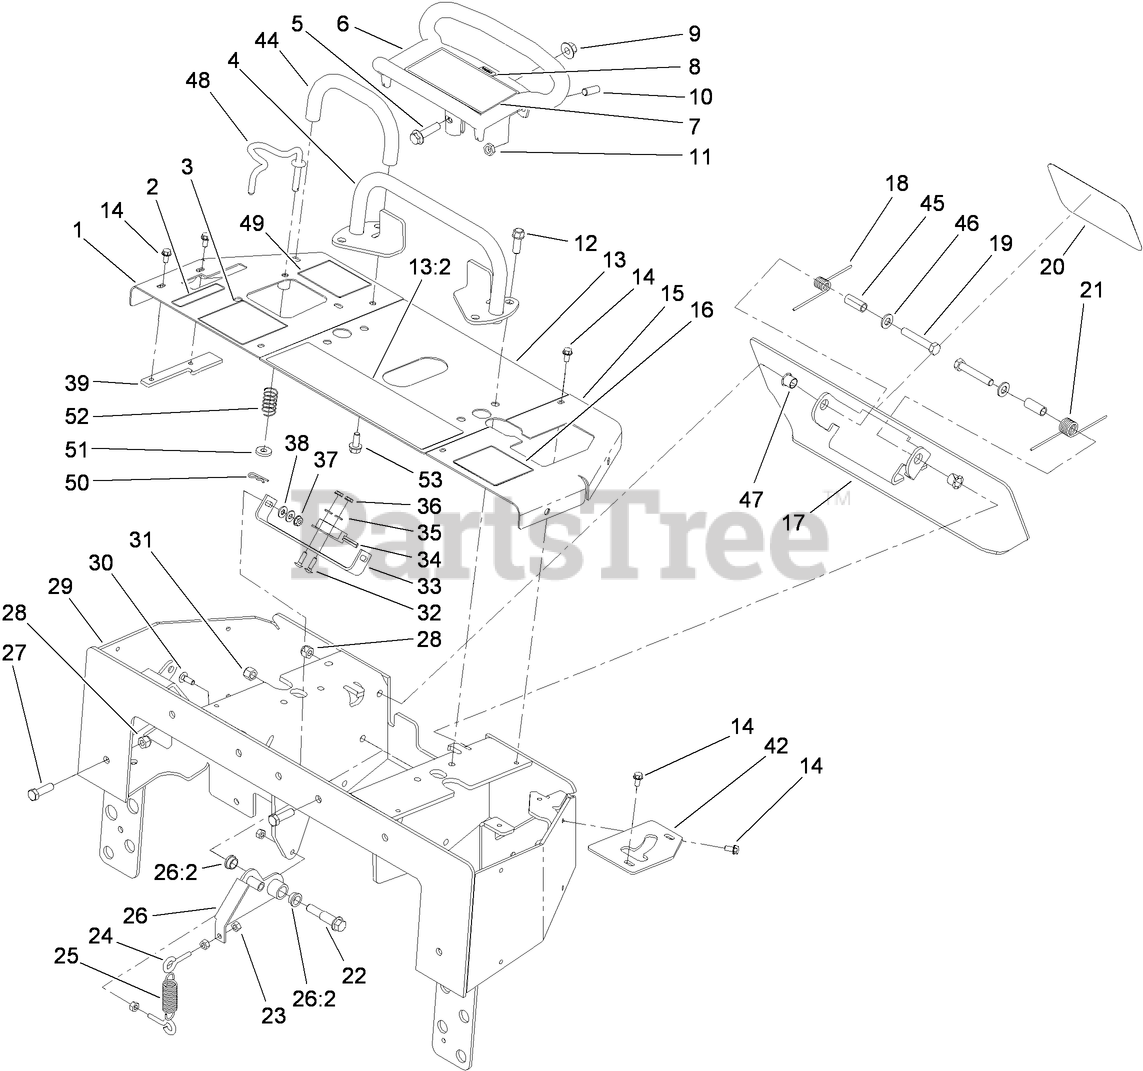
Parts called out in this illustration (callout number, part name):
1	PANEL-RH
2	DECAL-BRAKE
3	DECAL-CONTROL, LOADER
4	BAR-REFERENCE
5	SCREW-HHF
6	HANDLE-CONTROL
7	DECAL-TRACTION
8	DECAL
9	NUT-FLANGE
10	SCREW-SET
11	NUT-JAM
12	SCREW-TAPTITE
13	CENTER PANEL ASM
13:2	DECAL-DANGER
14	SCREW-HWH
15	PANEL-LH
16	DECAL-CONTROL, AUXILIARY
17	PLATE-REVERSE
18	SPRING-TORSION, LH
19	SCREW-HH
21	SPRING-TORSION, RH
22	BOLT-SHOULDER
23	NUT-HHF
24	BOLT-EYE
25	SPRING-EXTENSION
26	NEUTRAL CENTERING LEVER ASM
26:2	BUSHING-FLANGE
27	SCREW-HH
28	NUT-LOCK, NI
29	PANEL-CONTROL
30	BOLT-CARR
31	NUT-LOCK
32	SCREW-CARR
33	PLATE-SWITCH
34	SWITCH-PROXIMITY
35	WASHER-FLAT
36	NUT-KEPS
37	NUT-KEPS
38	WASHER-FLAT
39	PLATE-LOCKING, BRAKE
42	PLATE-STOP
44	BAR-REFERENCE
45	SPACER-SPRING
46	WASHER-FLAT
47	BUSHING-NYLINER
48	ROD-INTERLOCK
49	DECAL-LOADER LOCK
50	PIN-COTTER
51	WASHER-FLAT
52	SPRING-CONTROL
53	SCREW-HHF
